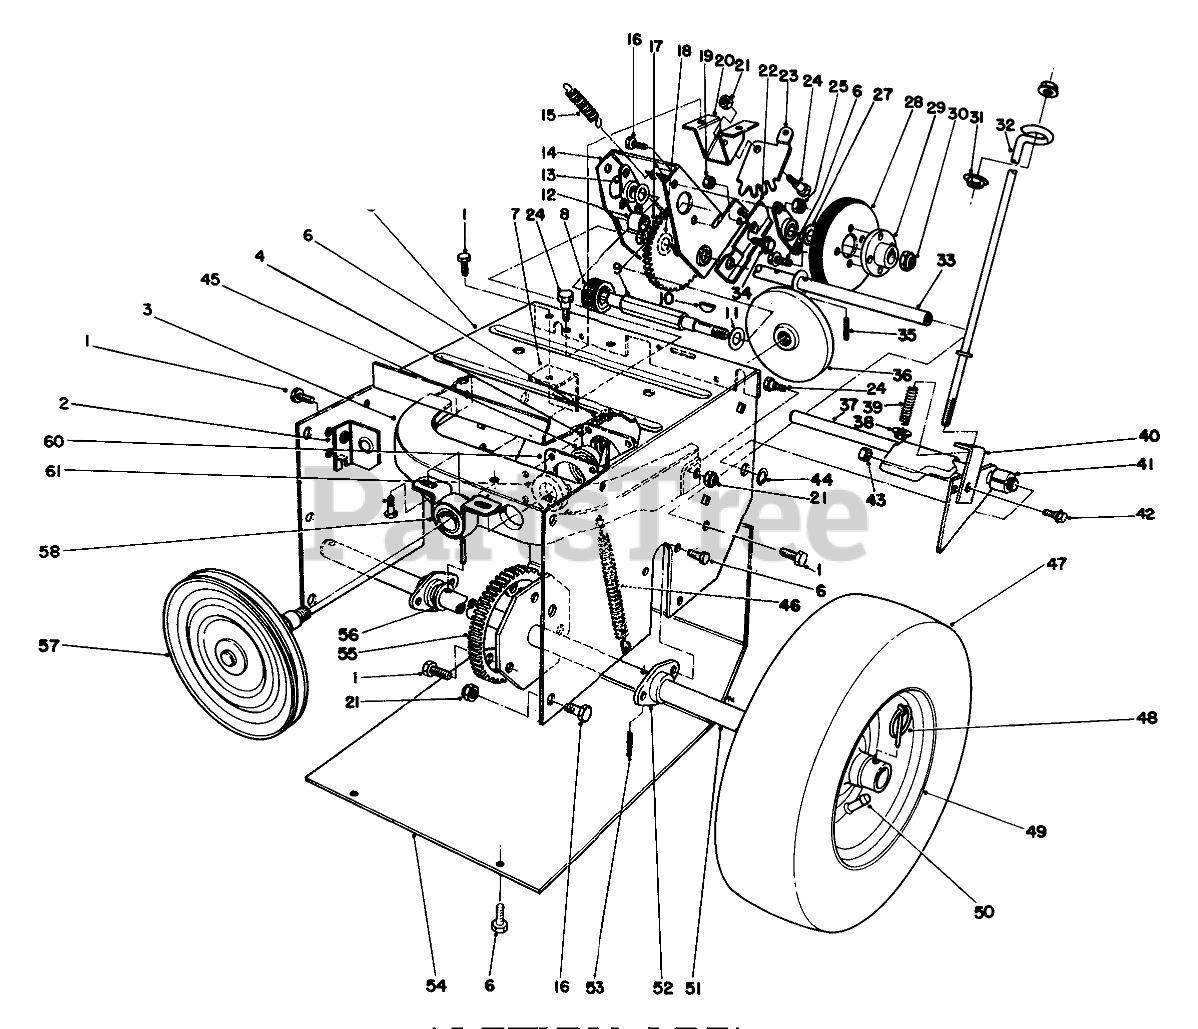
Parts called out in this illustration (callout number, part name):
1	SCREW-HWHTF
2	BRACKET-MOUNT, FRONT
3	"OBS" FRICTION PLT FRAME
4	CUP-BEARING
5	Frame-Traction
6	SCREW-HWH
7	BRACKET-MOUNT, REAR
8	PINION
9	SHAFT-WHEEL, FRICTION
10	KEY-WOODRUFF
11	WASHER-FLAT
12	5/8ID X 1LG BUSHING
13	BEARING-WHEEL, FRICTION
14	BRACKET-SLIDING
15	SPRING-TRACTION
16	SCREW-HH
17	Intermediate Gear & Bushing (Incl. Ref. #12)
18	WASHER-SPECIAL
19	NUT-LOCK, NI
20	MOUNT-LEVER
21	NUT-LOCK, NI
22	CAM-RECEIVER
23	GEAR-QUADRANT
24	BOLT-SHOULDER
25	NUT-LOCK, NI
27	WASHER-THRUST
28	WHEEL-FRICTION
29	HUB-WHEEL, FRICTION
30	NUT-LOCK, NI
31	NUT-HF
32	ROD-TRACTION, LOWER
33	SHAFT-PIVOT
34	SCREW-HH
35	PIN-SPRING
36	PLATE-FRICTION
37	Traction Engagement Asm.
38	NUT-HHF
39	SPRING
40	BRACKET-TRACTION
41	SPACER
42	SCREW
43	NUT-LOCK, NI
44	RING-RETAINING
45	BEARING-BALL
46	SPRING-PLATE, FRICTION
48	PIN-LYNCH
49	WHEEL
50	TUBE-INNER
51	SHAFT-AXLE
52	BEARING-AXLE
53	PIN-SPRING
54	Bottom Cover
55	GEAR-AXLE
56	WASHER-THRUST
57	Pulley & Shaft
58	BUSHING ASM
59	SCREW-HWHTF
60	BEARING GASKET
61	Gasket-Bearing
